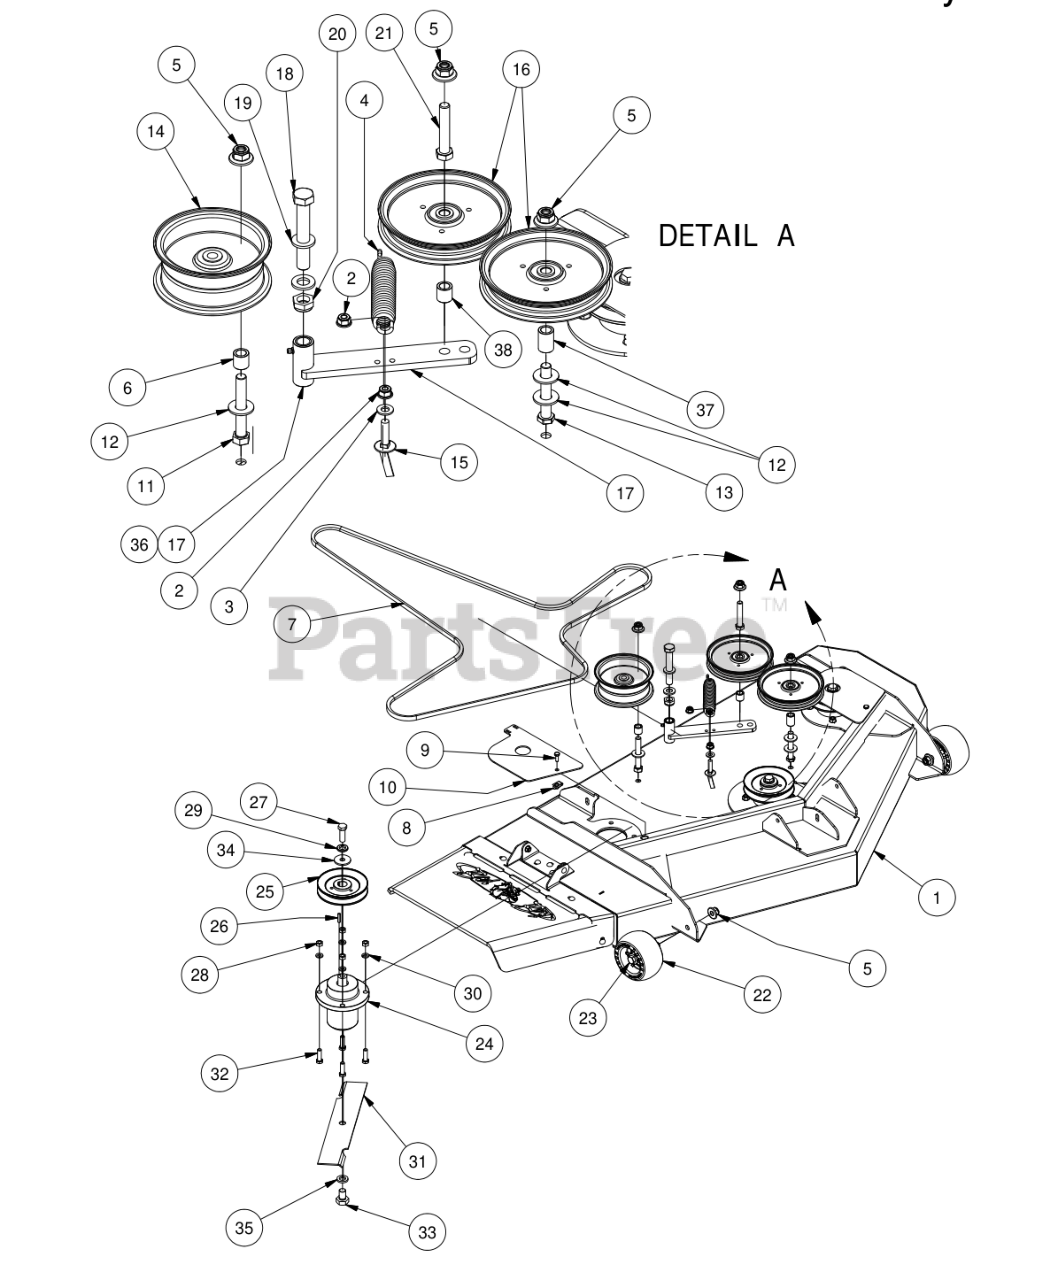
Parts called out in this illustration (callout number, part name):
1	48 MZ Deck (Component)
2	3/8" Nylock Flange Nut
3	3/8" Flat Washer
4	2009 Deck/Pump Idler Spring
5	1/2-13 Nylon Flange Nut
6	Spacer 3/4 OD x 1/2 ID x 3\4 Length
7	B128 Deck Belt
8	1/4-20 Cage Nut
9	1/4" x 3/4" Hex Bolt
10	MZ Pulley Cover 48"
11	1/2-13 x 3 1/2 GR 5 Hex Bolt
12	1/2" Washer (Grade 8)
13	1/2-13 x GR 5 Hex Bolt Zinc
14	5 3/4" Deck Idler Pulley
15	3/8 x 1-1/2 Carriage Bolt
16	5-3/4 Idler Pulley
17	Deck Idler Bracket
18	5/8" x 4" Hex Bolt
19	.635 ID Plastic Washer
20	5/8-11 Nylon Insert Jam Half Nut
21	1/2" x 2 3/4" Hex Bolt
22	Deck Wheel
23	Deck Wheel Bolt
24	Spindle Assembly
25	MZ Deck Pulley
26	3/16 x 1 Square Key
27	1/2-20 x 1-1/2 Grade 5 Hex Bolt Zinc
28	3/8-16 Hex Nuts Zinc
29	1/2" Lock Washer Zinc
30	3/8 Lockwasher Zinc
31	MZ 48 Blade
32	3/8" x 1 1/4" Hex Bolt
33	5/8" x 1 1/2" Grade 8 Hex Bolt (Fine)
34	1/2 Belleville Washer
35	5/8" Lock Washer
36	Deck Idler Assembly (5,16,17,21,and 39)
37	.502 x .750 x 1.25 Length Spacer
38	42/48 MZ Idler Pully Spacer
